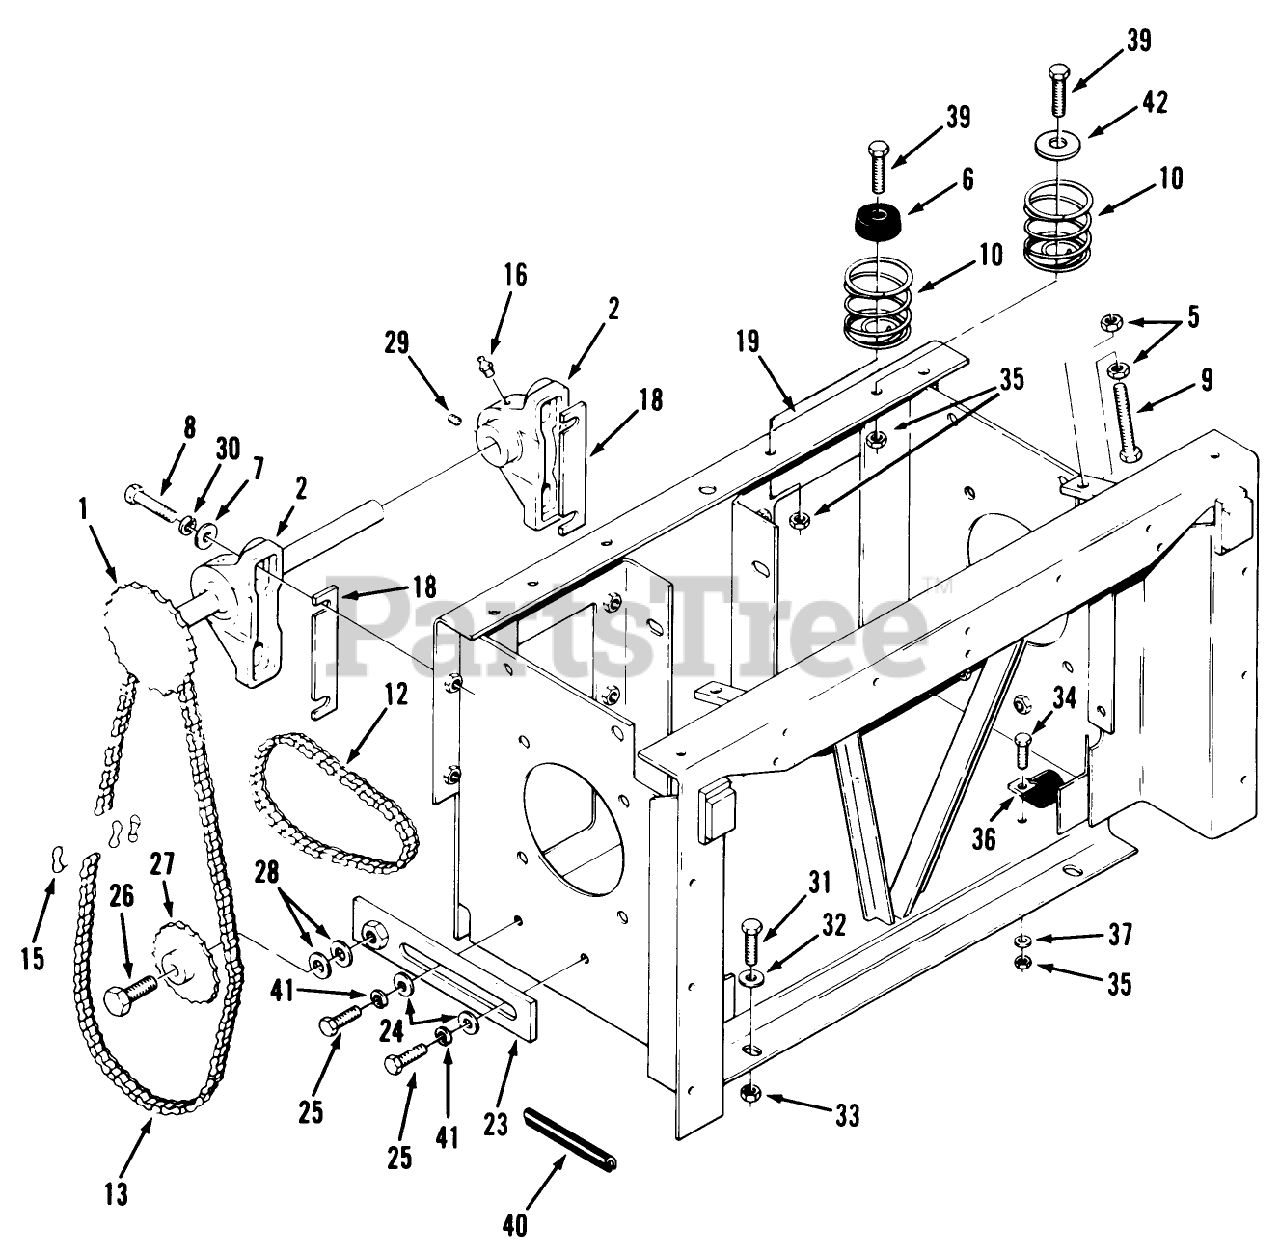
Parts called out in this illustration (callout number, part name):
1	ASSY-JACKSHAFT PLT
2	Pillow Block Bearing (Includes items 16 & 29)
5	Nut
6	BUMPER
7	Bolt
8	BOLT
9	Full Thread Bolt 5/16 x 1-1/2
10	SPRING-SEAT NYLON
12	CHAIN-#50 PRIMARY
13	ROLLER-CHAIN #50 SEC
15	CONNECTING LINK
16	Fitting-Grease
18	SHIM-PILLOW BLOCK
19	WLDMT-FRAME TRANS B
23	ASSY-CHAIN TENSIO B
24	Washer
25	BOLT
26	HEX HD CAP SCREW
27	IDLER SPROCKET 20288
28	WASHER
29	SCREW-SET
30	LOCKWASHER
31	BOLT
32	Washer
33	NUT
34	Bolt
35	Nut
36	CLIP
37	WASHER 5/16 SAE
39	Bolt
40	EDGE TRIM
41	LOCKWASHER
42	WASHER
